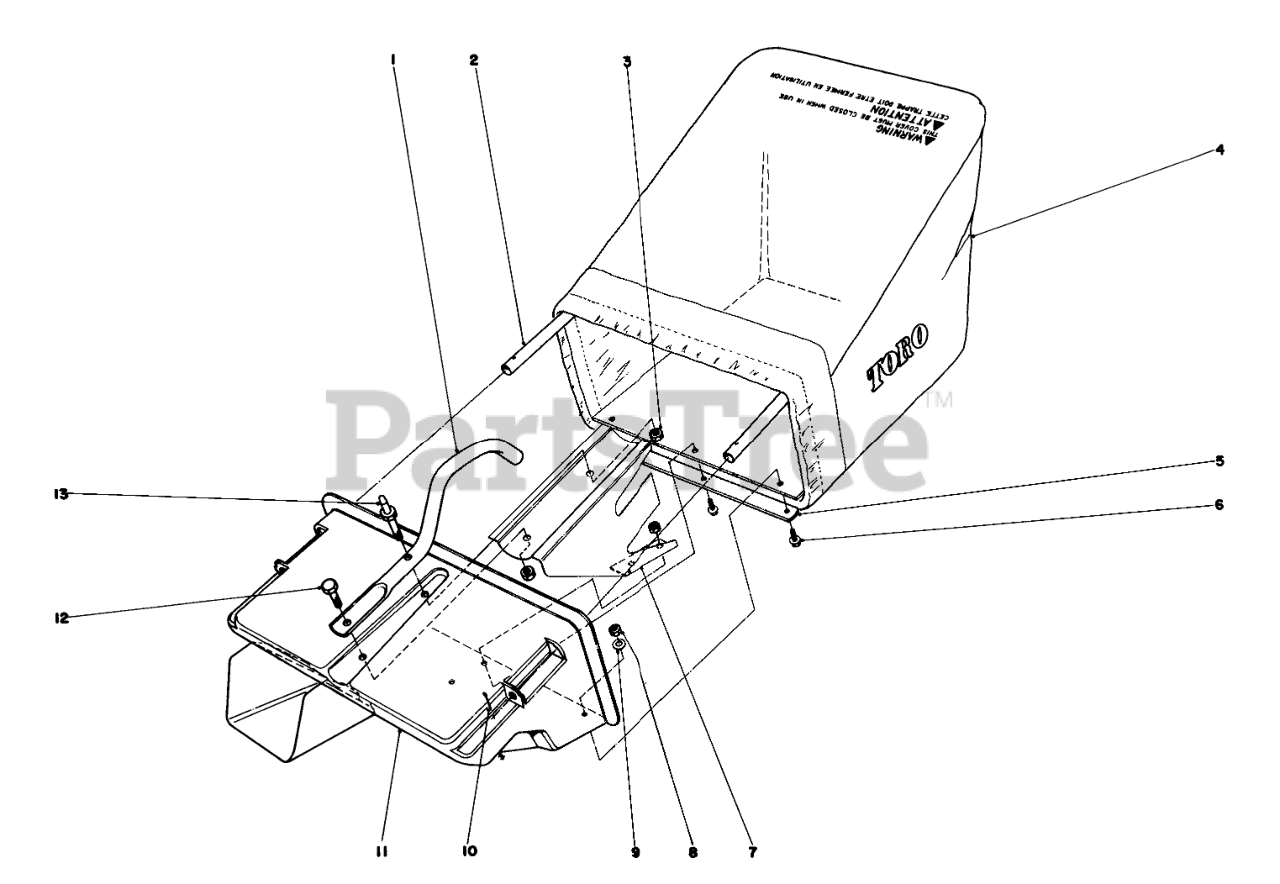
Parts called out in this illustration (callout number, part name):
1	BAG HANDLE
2	BAG FRAME
3	Nut
4	Grass Bag
5	BAG RETAINER
6	SCREW-HWH
7	BAFFLE-BAG SHELL
8	Nut
9	WASHER-FLAT
10	PIN-COTTER
11	Bag Shell
12	SCREW-HH
13	HANDLE STUD
